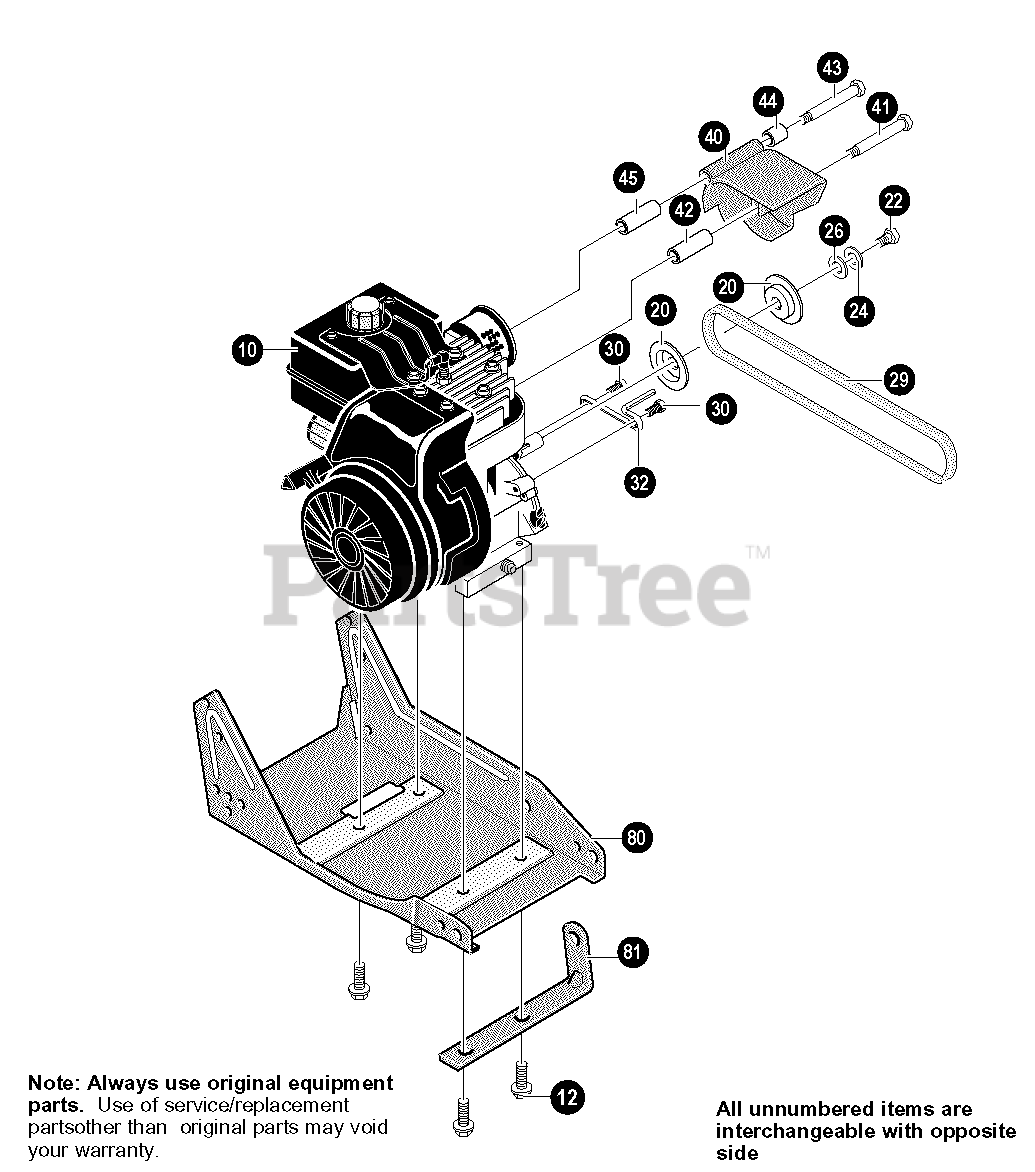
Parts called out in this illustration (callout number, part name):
10	3.5HP
12	Screw, 3/8-16 x 1.00
20	Pulley, Half V3L
22	Screw, 5/16-24x 1.00
24	Washer, .328x.60x.09
26	Flatwasher .333x.87x.119
29	Belt, V 4L 32.60LG
30	Screw and Washer Assy
32	Belt Guide
40	Cover, Engine Pulley
41	Screw, 5/16-24x3.00
42	Spacer, Sleeve .335x.431x2.50
43	Screw, 5/16-24x3.75
44	Spacer, .322ID .562 OD
45	Spacer, Sleeve .335x.431x2.50
80	Frame, Assy Edger
